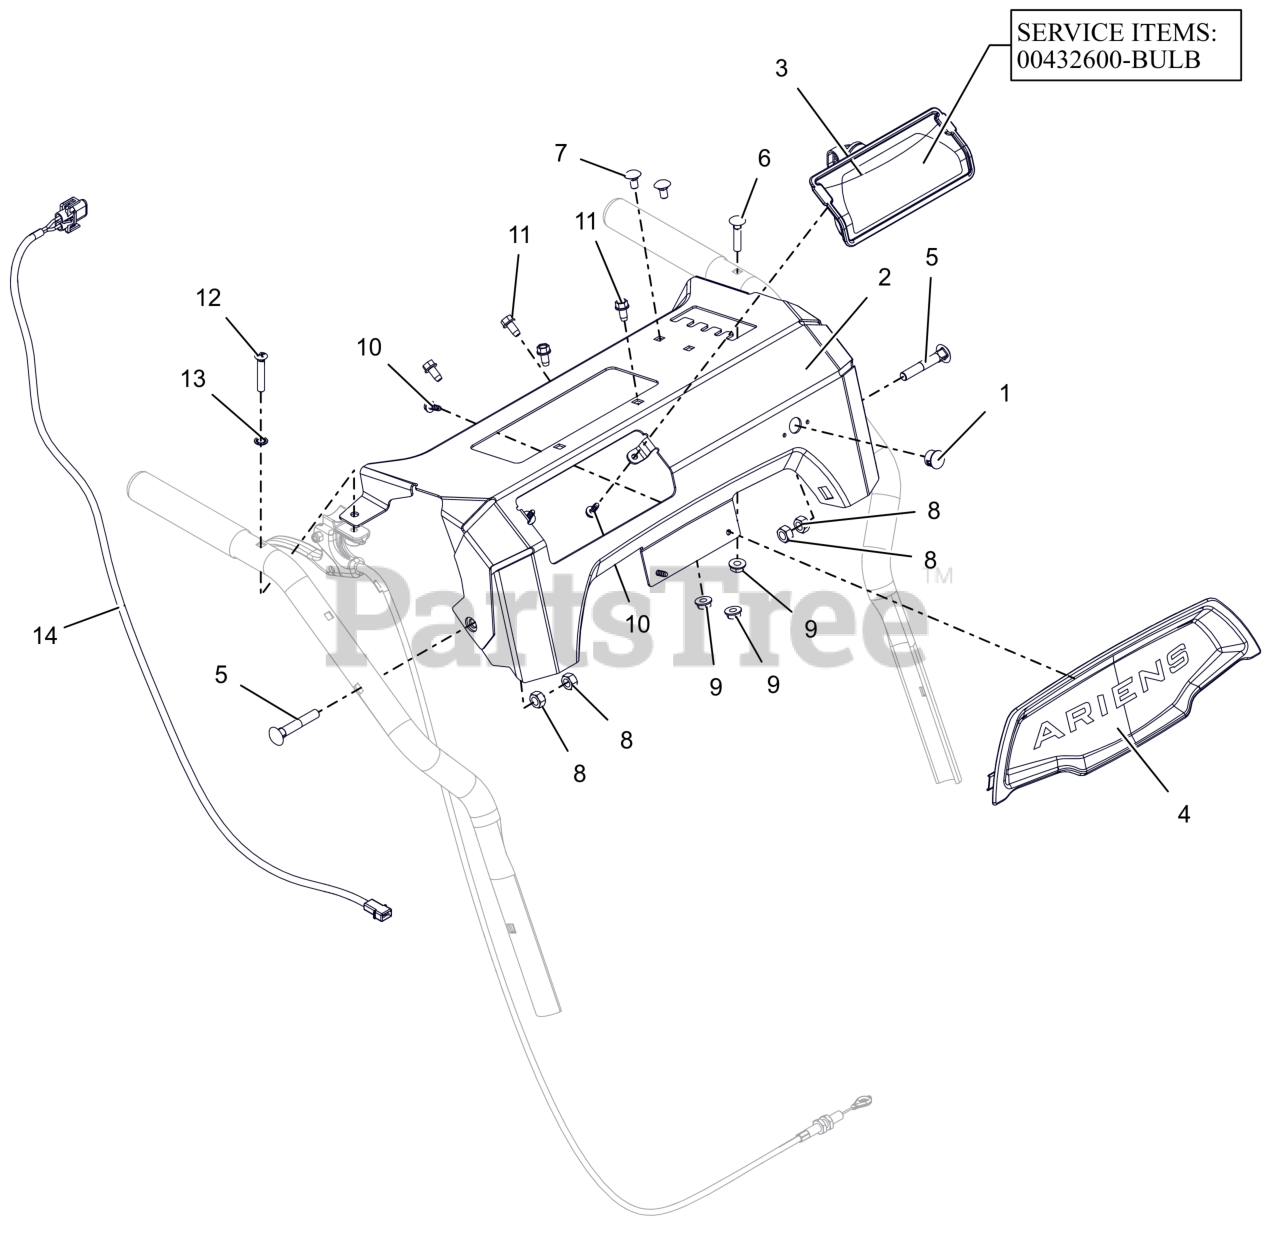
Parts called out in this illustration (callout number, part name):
1	HOLE PLUG, PLASTIC .56 HOLE
2	CTRL PANEL W/DECAL-COMP TRACK
3	HEADLIGHT ASY, HALO 20W 2SHOT
3	BULB, LIGHT-HALOGEN 20W
4	BEZEL, DASH - ARIENS SM DASH
5	BLT-RDHDXLSQNK .31-18X2.0 G5YZ
6	BLT-RDHDXLSQNK.25-20X1.25 G5ZC
7	BLT, RHSN .25-20X.500 G5 ZCC
8	NUT,LK-CTR .31-18 GA ZCC
9	NUT-LK-TOP-FLG .250-20 GF ZCC
10	SCR, PLASTIC #10X.50
11	SCR-TAP .25-20X.50 HWH ZCC
12	SCR,OVAL .25-20X1.50 ZCC
13	WSHR-LK-INT .250 TH TYA
14	HARNESS, LIGHT - COMPACT
